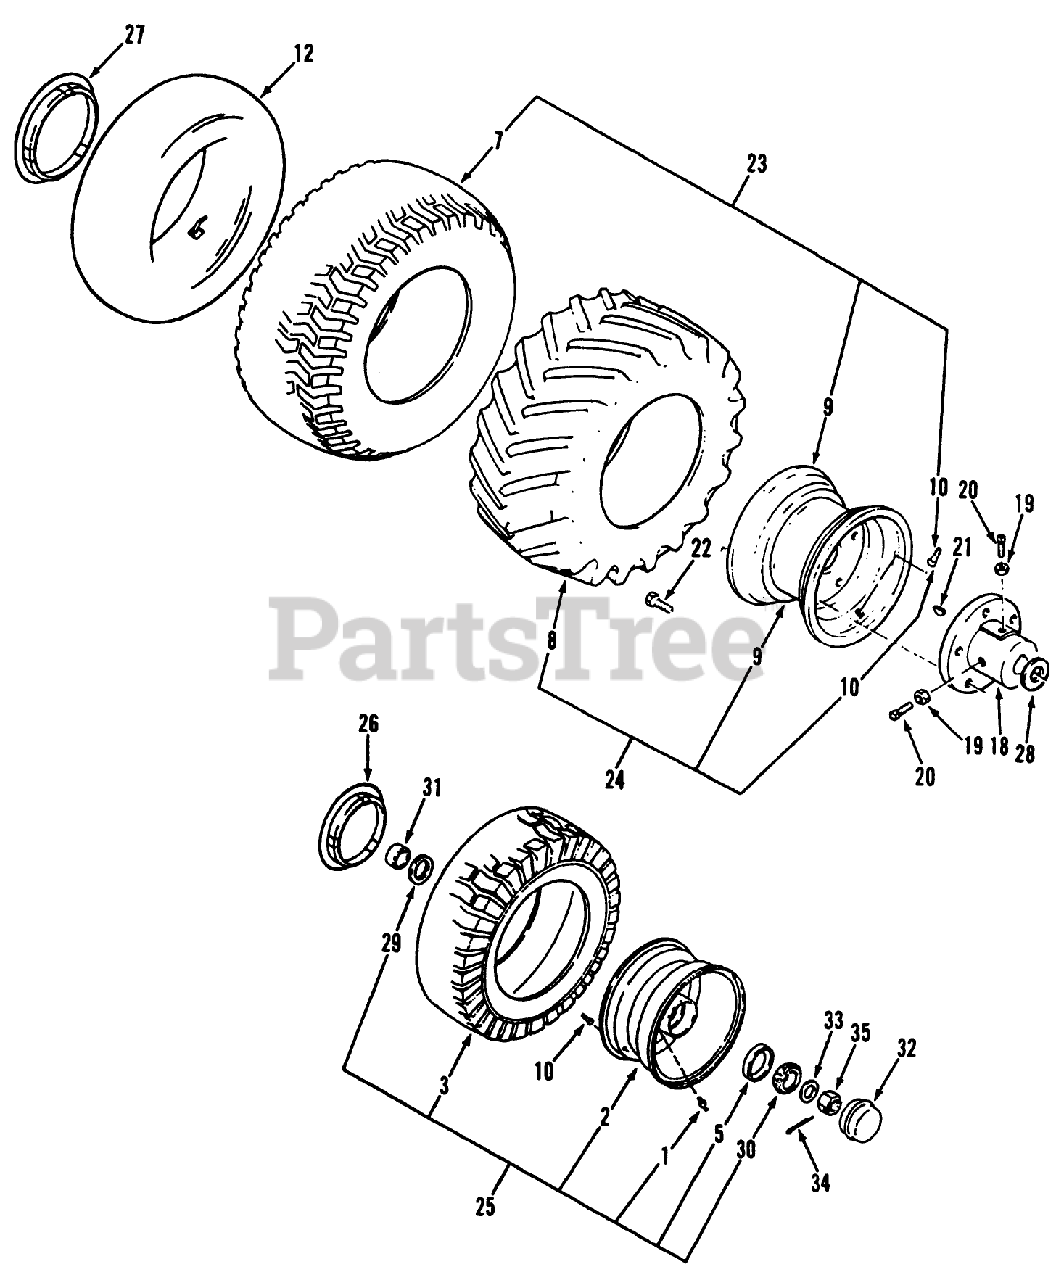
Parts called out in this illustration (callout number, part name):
1	ZERK-GREASE
9	RIM ASM
10	VALVE
19	NUT-JAM
20	SCREW-SET, SQH
21	KEY-WOODRUFF
23	Rear Wheel Tire Assy
28	WASHER-THRUST
31	SPACER
32	DUST CAP
34	PIN-COTTER
35	NUT-HEX, SLOTTED
